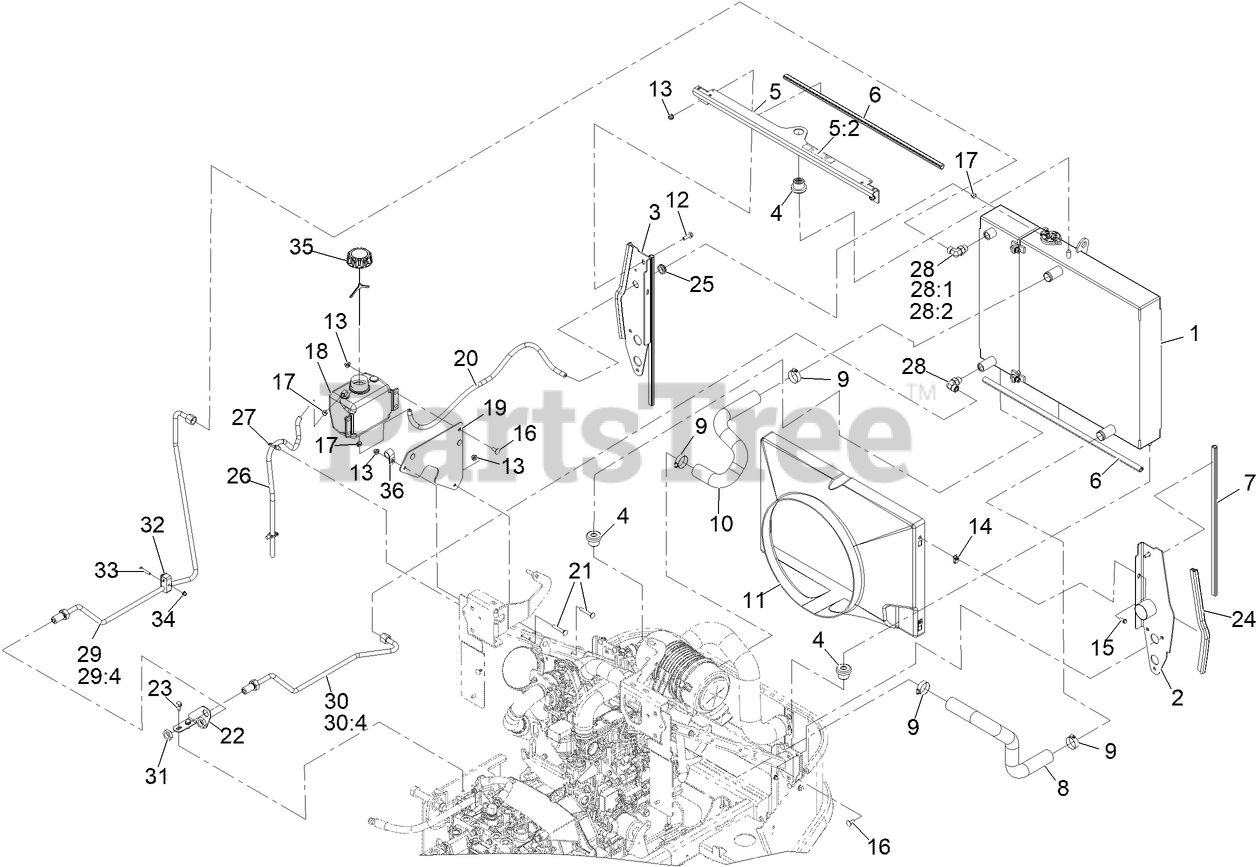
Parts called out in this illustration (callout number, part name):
1	COOLING ASM
2	SUPPORT-RADIATOR, LH
3	SUPPORT-RADIATOR, RH
4	MOUNT-ISOLATOR
5	Bracket-Top Cooling
5:2	Decal-Warning
6	SEAL-BULB
7	SEAL-BULB
8	HOSE-RADIATOR, LOWER
9	CLAMP-HOSE
10	HOSE-RADIATOR, UPPER
11	SHROUD-FAN
12	SCREW-HHF
13	NUT-HF, NI
15	SCREW-HWH
16	SCREW-CARR
17	CLAMP-HOSE
18	TANK-OVERFLOW, W/CAP
19	BRACKET-BOTTLE
20	HOSE-FUEL
21	BOLT-CARR
22	BRACKET-BULKHEAD
23	Screw-HWH 5/16-18 X 3/4 Tf
24	SEAL-BULB
25	GROMMET
26	HOSE-FUEL
27	CLIP-TIE
28	FITTING-ELBOW, 90 DEG
28:1	O-RING
28:2	O-RING
29	HYDRAULIC TUBE ASM
29:4	O-RING
30	HYDRAULIC TUBE ASM
30:4	O-RING
31	NUT-BULKHEAD
32	CLAMP-TWIN
33	SCREW-HH
35	CAP-W/TETHER
36	CLIP-LOOM
